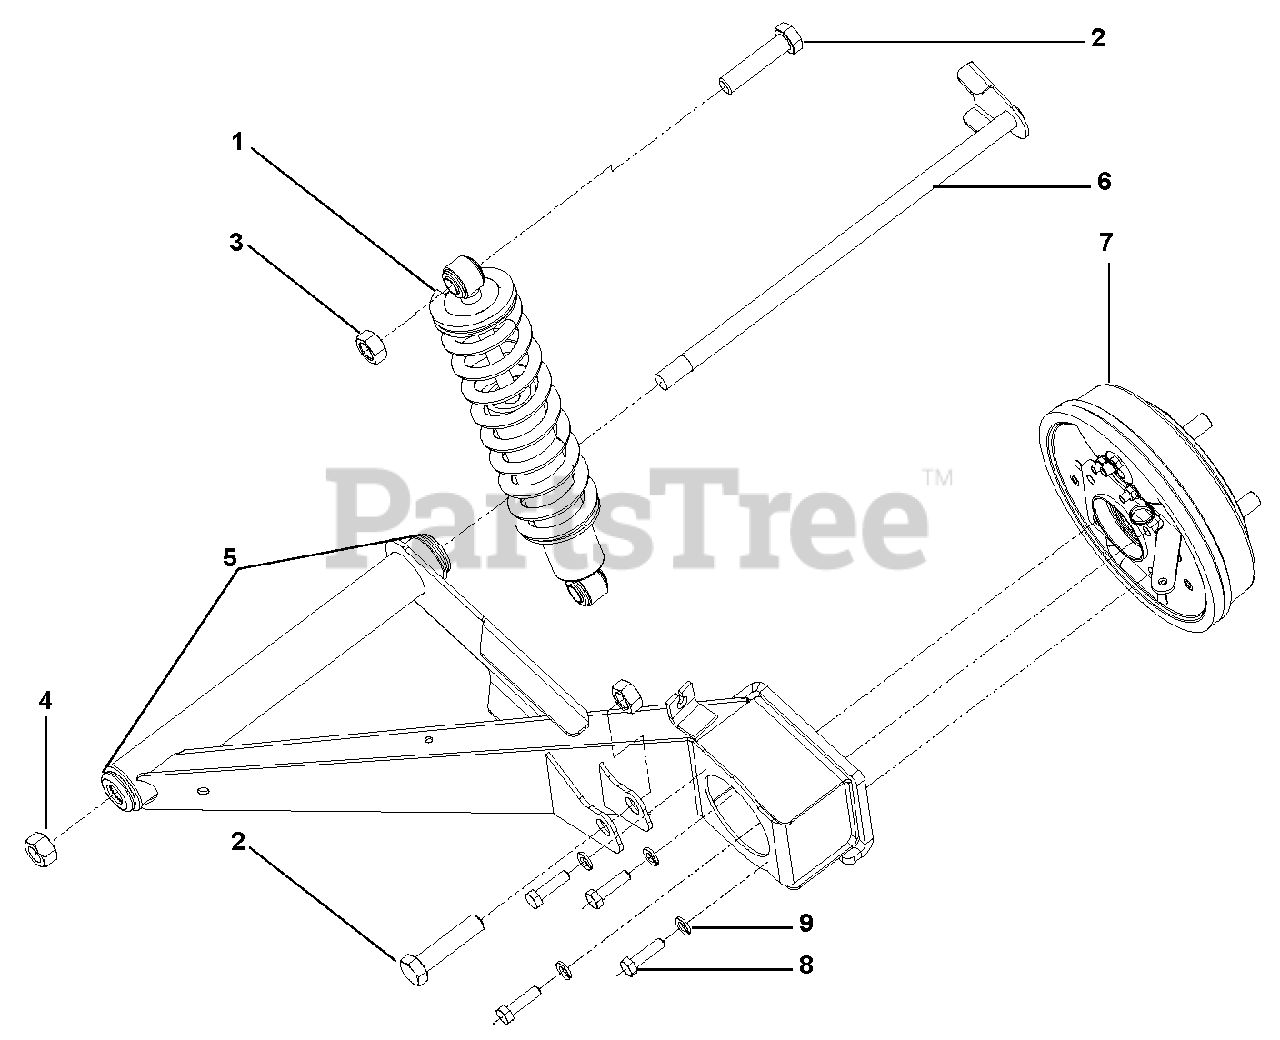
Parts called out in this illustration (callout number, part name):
1	SHOCK, COIL REAR TRUCK
2	HHCS M14 X 2.00 X 60 GR8.8
3	NUT, HEX NYLOCK M14 X 2.00
4	NUT, LOCK TOP .563-12 GR5 YWZC
5	BUSHING IDLER ARM RUBBER
6	CENTER PIVOT TUBE WELDMENT
7	RIGHT HAND DRUM ASM 18 OMM 4 ON 4" BC
8	HHCS M8 X 1.25 X 30 GR 10.9 YLW PLT
9	WASHER, LOCK M8 YWZC
